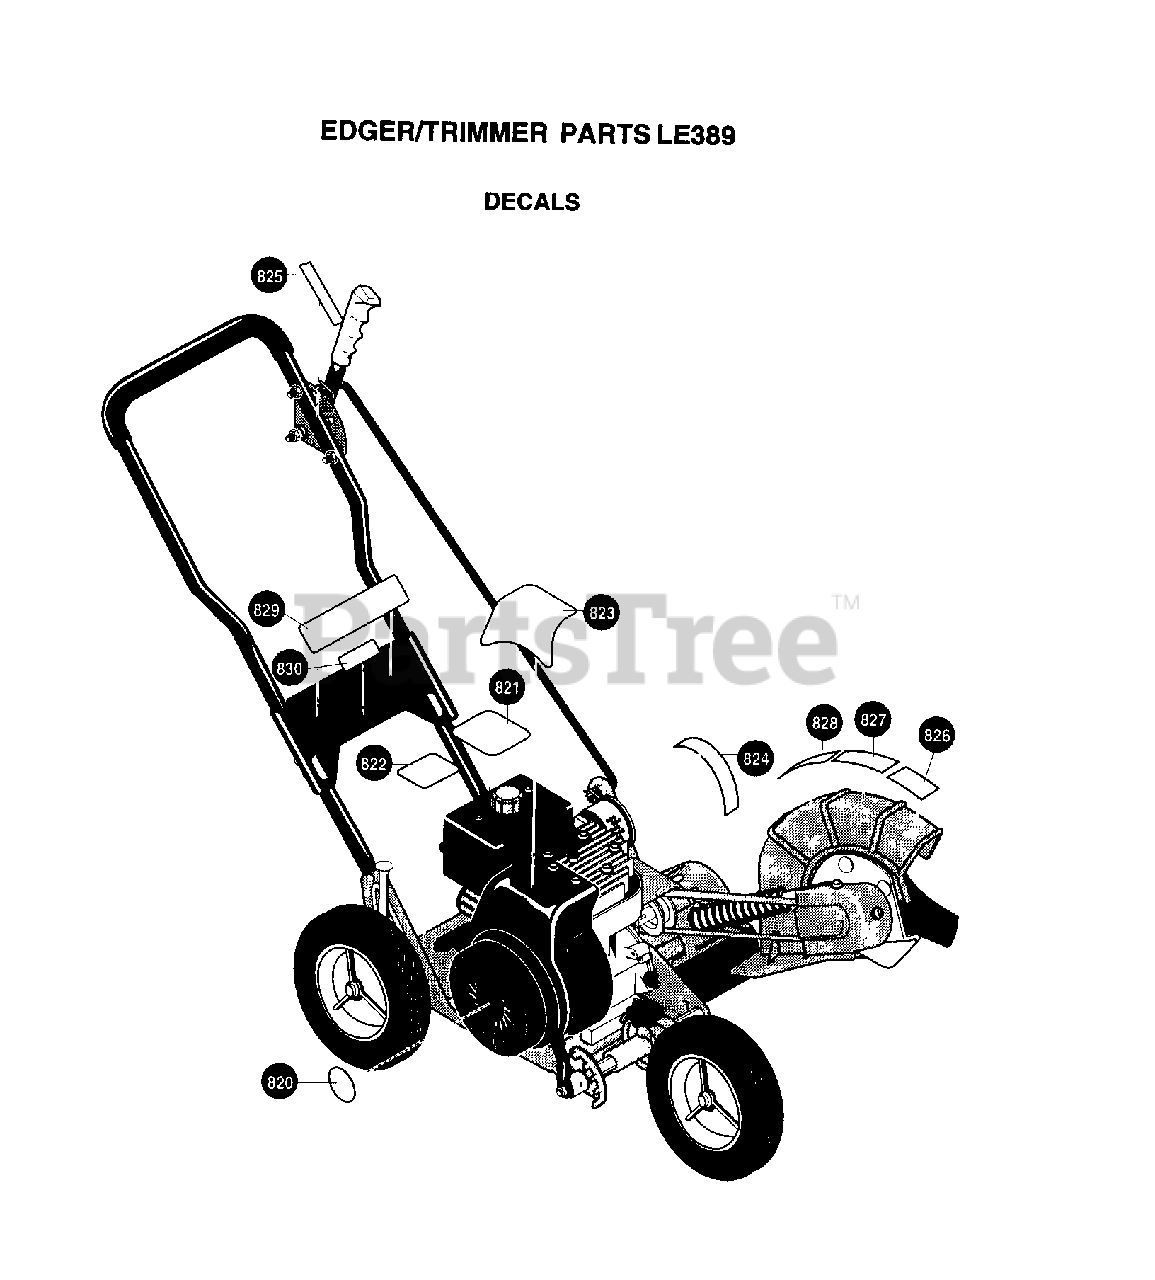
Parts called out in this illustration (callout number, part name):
820	Decal, Recoil Cover
821	Decal, Information Danger
823	Decal, Engine
824	Decal, Angle Indicator
825	Decal, Quadrant Selector
826	Decal, Blade Guard
829	Decal, Panel
830	Decal, Husq LE389
